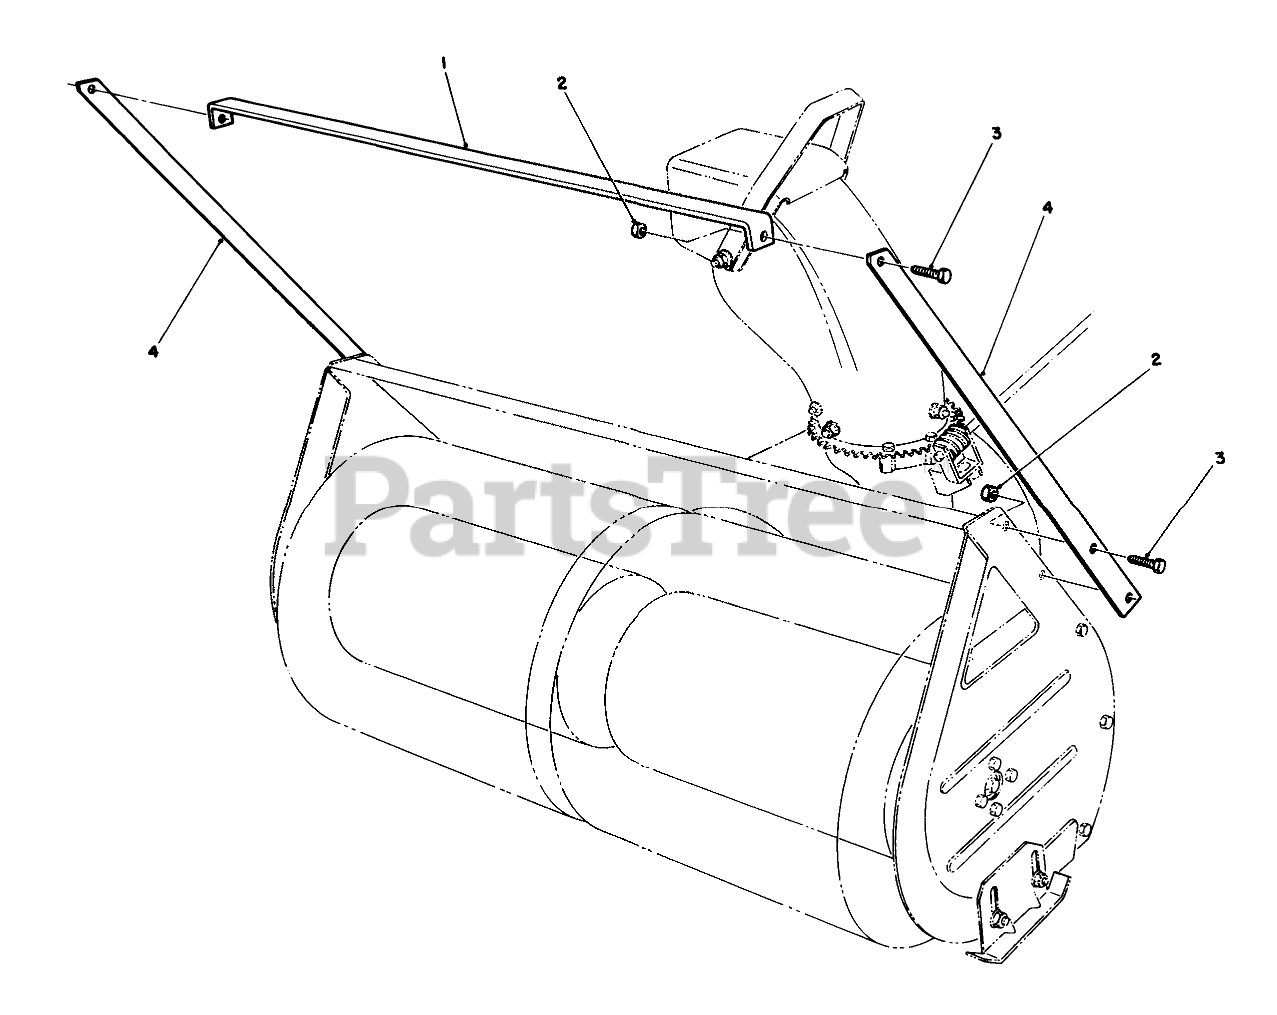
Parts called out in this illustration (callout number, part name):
1	32 TOP DRIFT BREAKER
2	NUT-LOCK, CONE
3	SCREW-HH
4	SIDE DRIFT BREAKER
